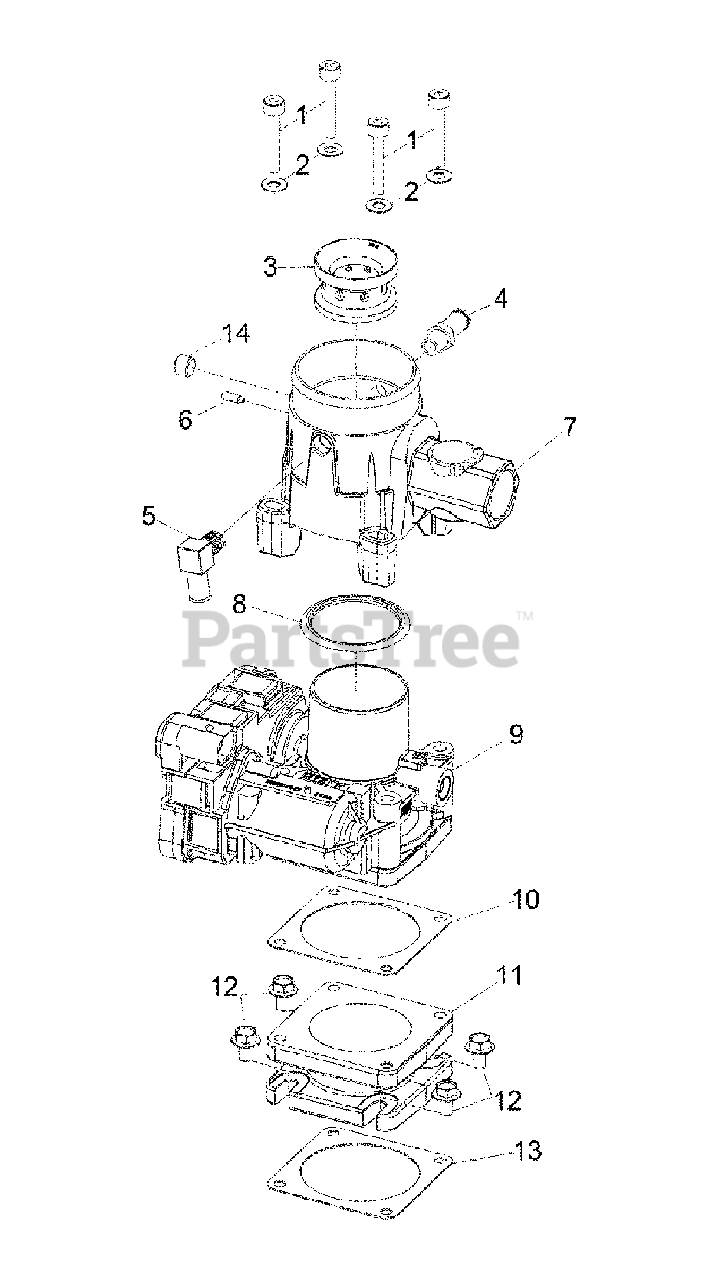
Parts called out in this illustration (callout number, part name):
1	SCREW
2	WASHER
9	THROTTLE BOTTLE
12	SCREW
